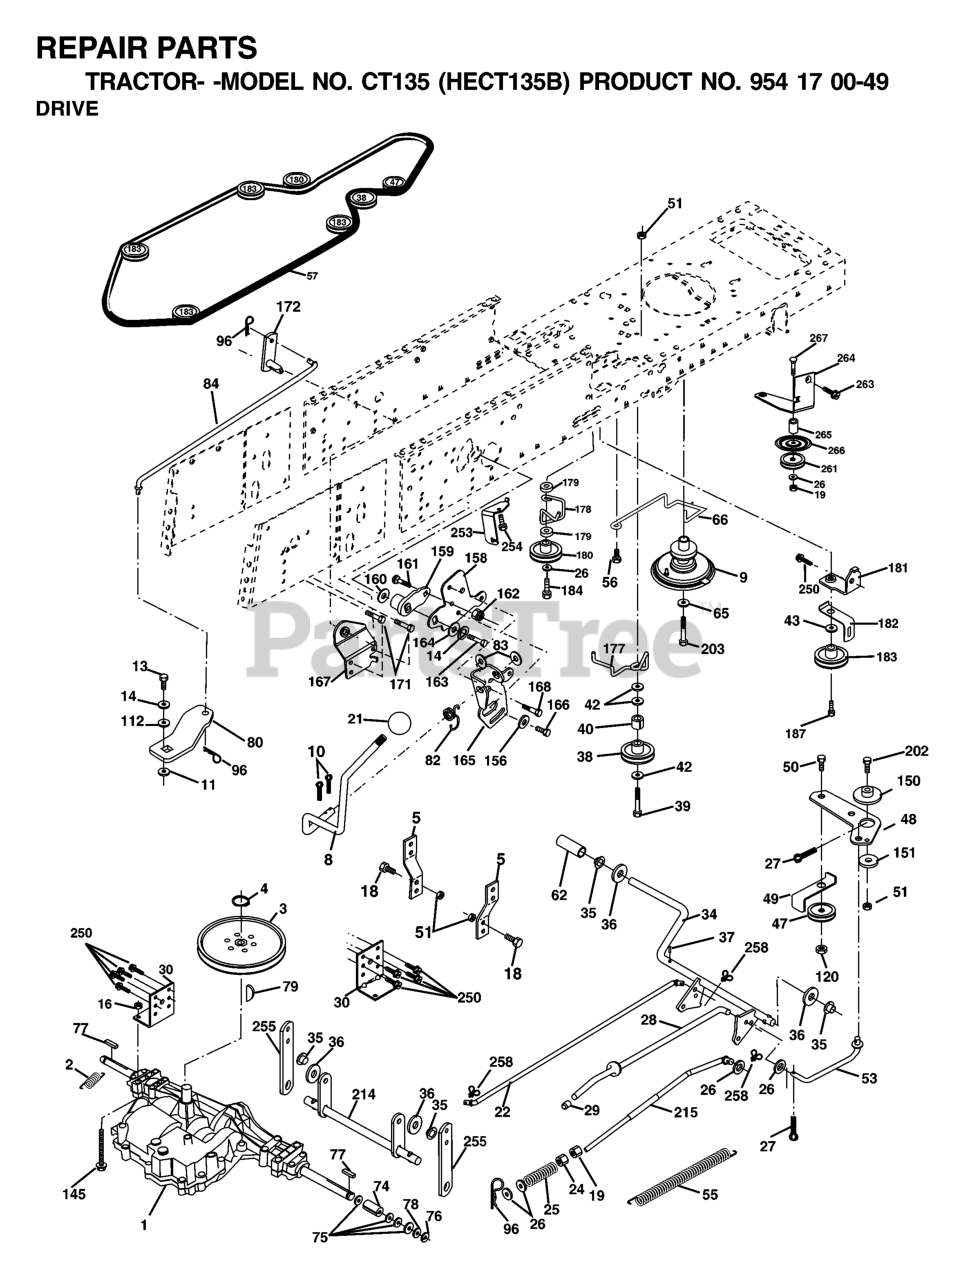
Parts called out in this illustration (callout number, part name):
2	SPRING,BRAKE RETURN
3	PULLEY
4	RETAINING RING LT
5	STRAP TORQUE
8	ROD.SHIFT.FENDER.ADJ.LT.CRD
9	RP CLUTCH.NORAM.2002
10	PIN COTTER
11	WASH-SHFT PLT LT
13	BOLT 1/4-28X3/4
14	LOCKWASHER
16	NUT.71038.31-18.HEX.NYLOCK
18	BOLT
19	NUT
21	KNOB.DUCKHEAD.1/2
22	ROD
24	NUT
25	SPRING ROD LT
26	WASHER
27	COTTER PIN
28	ROD, PARKING BRAKE
29	PLUNGER CAP
30	BRKT, MOUNT TRNSAXLE
34	SHAFT, FOOT PEDAL
35	BEARING.NYLON
36	WASHER LT
37	DRIVE PIN
38	PULLEY.FLAT
42	WASHER
43	WASHER T
47	IDLER PULLEY
48	BELLCRANK, CLUTCH
49	RETAIN BELT
50	BOLT
53	LINK, CLUTCH LT
55	SPRING, RETURN LT
56	SCREW.3/8-16
57	V-BELT.KEV.111"
62	COVER, PEDAL (1 2)
65	LOCKWASHER
66	KEEPER BELT ENGINE
74	SPACER AXLE
77	SQUARE KEY
79	KEY STD (1373) DANA
82	SHIFT SPRING
83	WASHER
96	RETAINER M
112	WASHER LT
120	NUT LOCK FLG 3/8-16 UNC
145	BOLT
150	BUSHING.BELLCRANK.GRD.DR
151	WASHER 12/32X2X10GA
156	WASHER.SRRTD.5/16
158	BRACKET
159	HUB
160	Washer 29/32 x 1 - 1/4 x 16 Ga.
161	BOLT
162	NUT.CROWNLOCK.1/4
163	BOLT
164	Washer 5/8 x .281 x 10 Ga.
165	RP BRACKET
167	BRACKET.SUPT.SHIFT.CRD
168	BOLT.SHOULDER.5/16-18X
171	SCREW LT
172	SHAFT
180	PULLEY.FLAT.IDLER
181	BRACKET
182	KEEPER BELT
184	SCREW.HXWSH.3/8
187	BOLT.5/16-18X1.25
203	BOLT.HEX.7/16-20 X 5
214	LEVER
250	SCREW 3/8-16X3/4
254	SCREW THDROL 3/8-16 X 1-1/2
255	SHAFT
258	CLIP RETAINER
261	FLAT IDLER PULLEY
263	SCREW LT
265	SPACER IDLER
266	PROTECTOR
267	BOLT.SS.CARR.3/8-16X3.25.GR5
